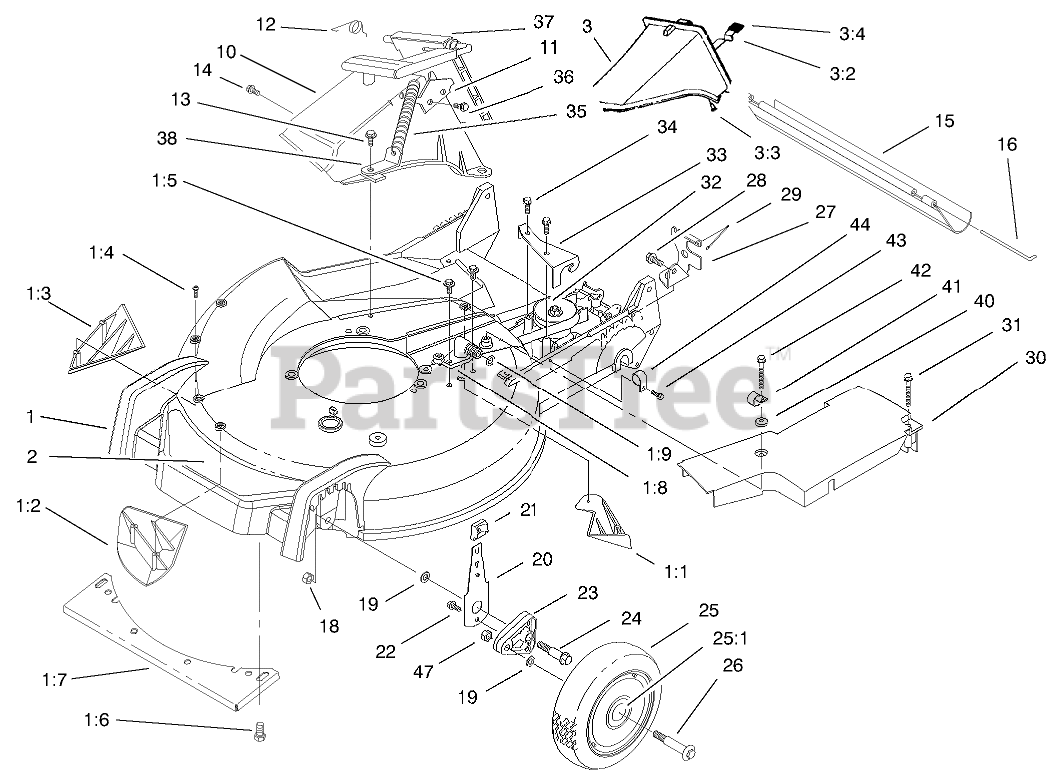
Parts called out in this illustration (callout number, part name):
1	HOUSING ASM
1:1	KICKER-REAR
1:2	KICKER-FRONT
1:3	KICKER-RH
1:4	SCREW-PPH
1:5	SCREW-HWH
1:6	SCREW-HWHTF
1:8	FITTING-WASHOUT
1:9	O-RING
2	DECAL - DECK
3	DISCHARGE PLUG ASM
3:2	LATCH-PLUG, DISCHARGE
3:3	RIVET-HEAD, FLAT
3:4	GRIP-LATCH
10	TUNNEL-DISCHARGE
11	LATCH-PLATE
12	RETAINER-DOOR
14	SCREW AND WASHER ASM
15	SHIELD-TRAILING
16	ROD-SHIELD
18	NUT-LOCK
19	WASHER
20	FRONT SPRING ARM ASM
21	KNOB-ARM
22	SCREW-HWH
23	ARM-PIVOT, FRONT
24	BOLT-SHOULDER
25	WHEEL ASM
25:1	BUSHING
26	BOLT-SHOULDER
27	Bracket-Adj. Trac
28	SCREW-HWHTF
29	RETAINER-CABLE
30	COVER-BELT
31	SCREW-HHFTF
32	GEARCASE ASM
33	Bracket-Guide
34	SCREW-HWHTF
35	SPRING-DOOR
36	SCREW-PLASTITE
37	DISCHARGE DOOR ASM
38	BRACKET-SPRING
40	WASHER
41	CLAMP-CABLE
42	SCREW-SPECIAL
43	SCREW-HWH
44	CLAMP-CABLE
